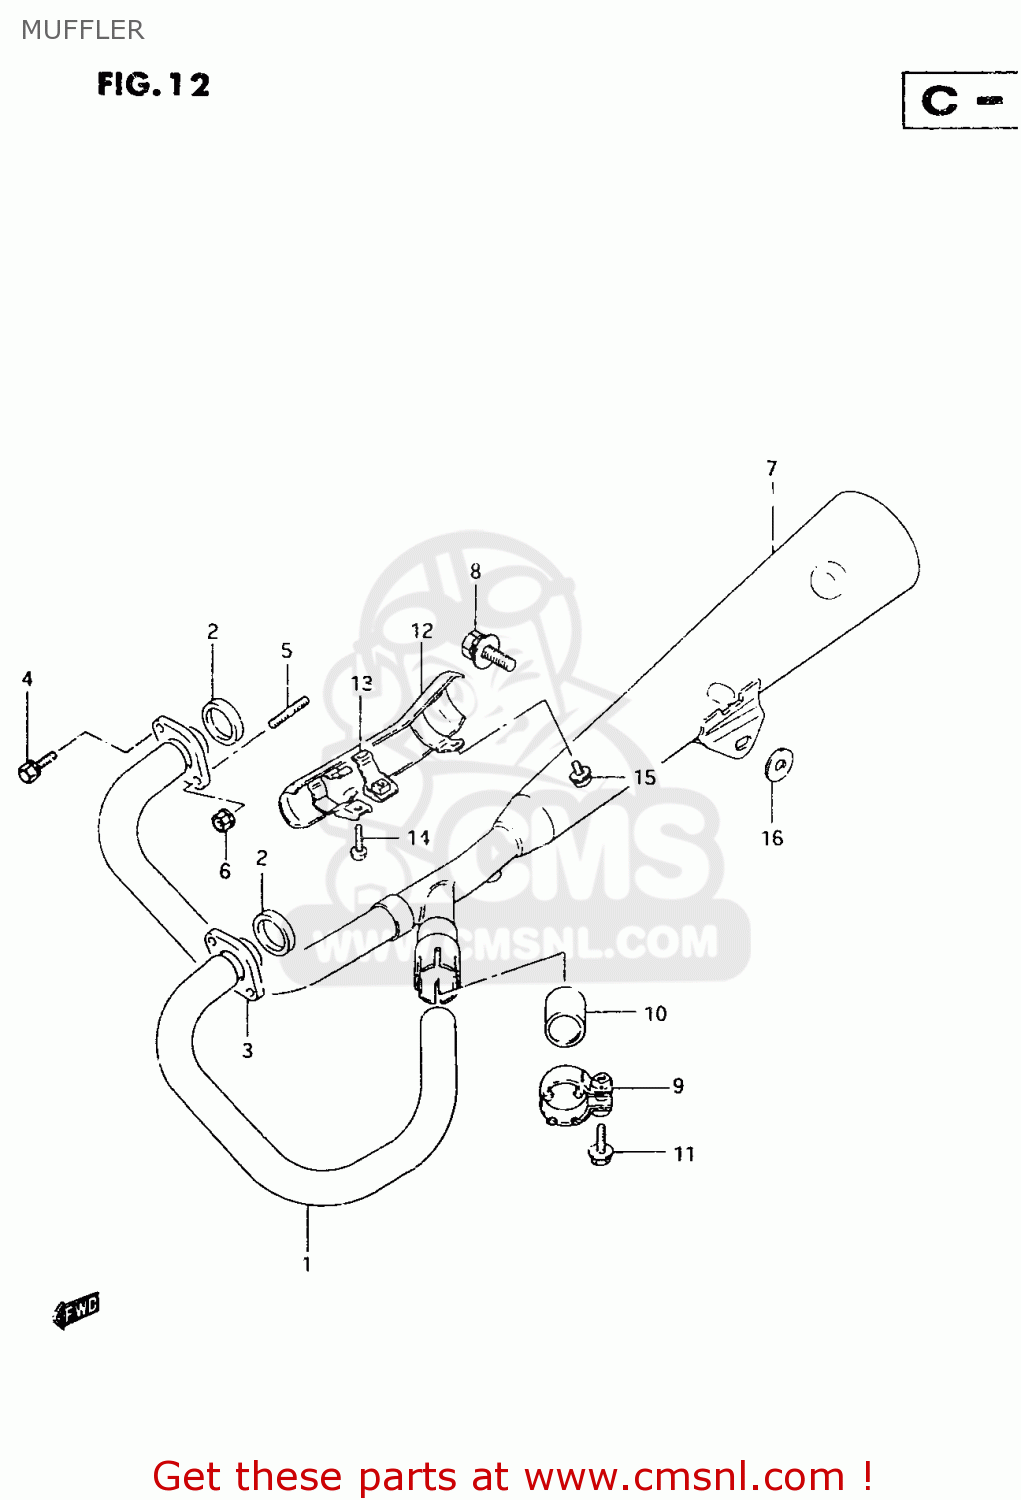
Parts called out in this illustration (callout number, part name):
1	PIPE,EXHAUST,L
2	GASKET,EXHAUST PIPE (NAS)
3	CLAMP
4	BOLT
5	BOLT,STUD
6	NUT.EXH PIPE
7	MUFFLER COMP
8	BOLT
9	CLAMP
10	CONNECTOR,MUFFLER
11	BOLT
12	COVER,MUFFLER
13	CLAMP,MUFFLER COVER
14	SCREW
15	SCREW
16	WASHER
